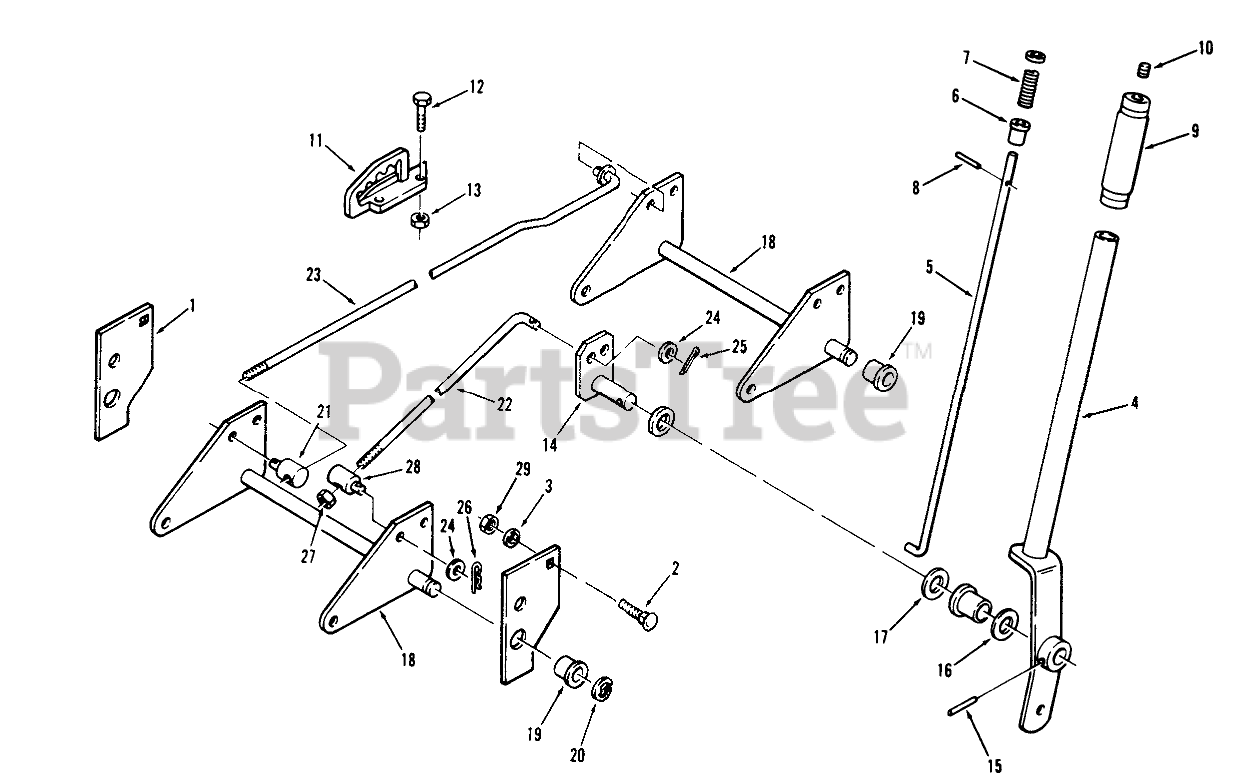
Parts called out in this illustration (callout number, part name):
1	Front Hitch Plate
2	Bolt-Carriage
3	Washer
4	Lift Lever
5	ROD-LATCH LIFT LEVER
6	RETAINER-SPRING
7	SPRING-COMPRESSION
8	PIN-SPIROL
9	HANDGRIP
10	CAP-ROD, PLUNGER
11	Height Control Quadrant
12	BOLT
13	Nut
14	Assy-Lift Arm
15	PIN-ROLL, SPIROL
16	WASHER
17	Washer
18	Assy-Lift Bell Crank
19	BRONZE BUSHING
20	E Ring
21	TRUNNION
22	LIFT ROD-FRONT
23	Lift Rod-Rear
24	Washer
25	Pop Rivet
26	Hairpin
27	NUT
28	TRUNNION-LIFT
29	Eslok Nut 1/4-20
